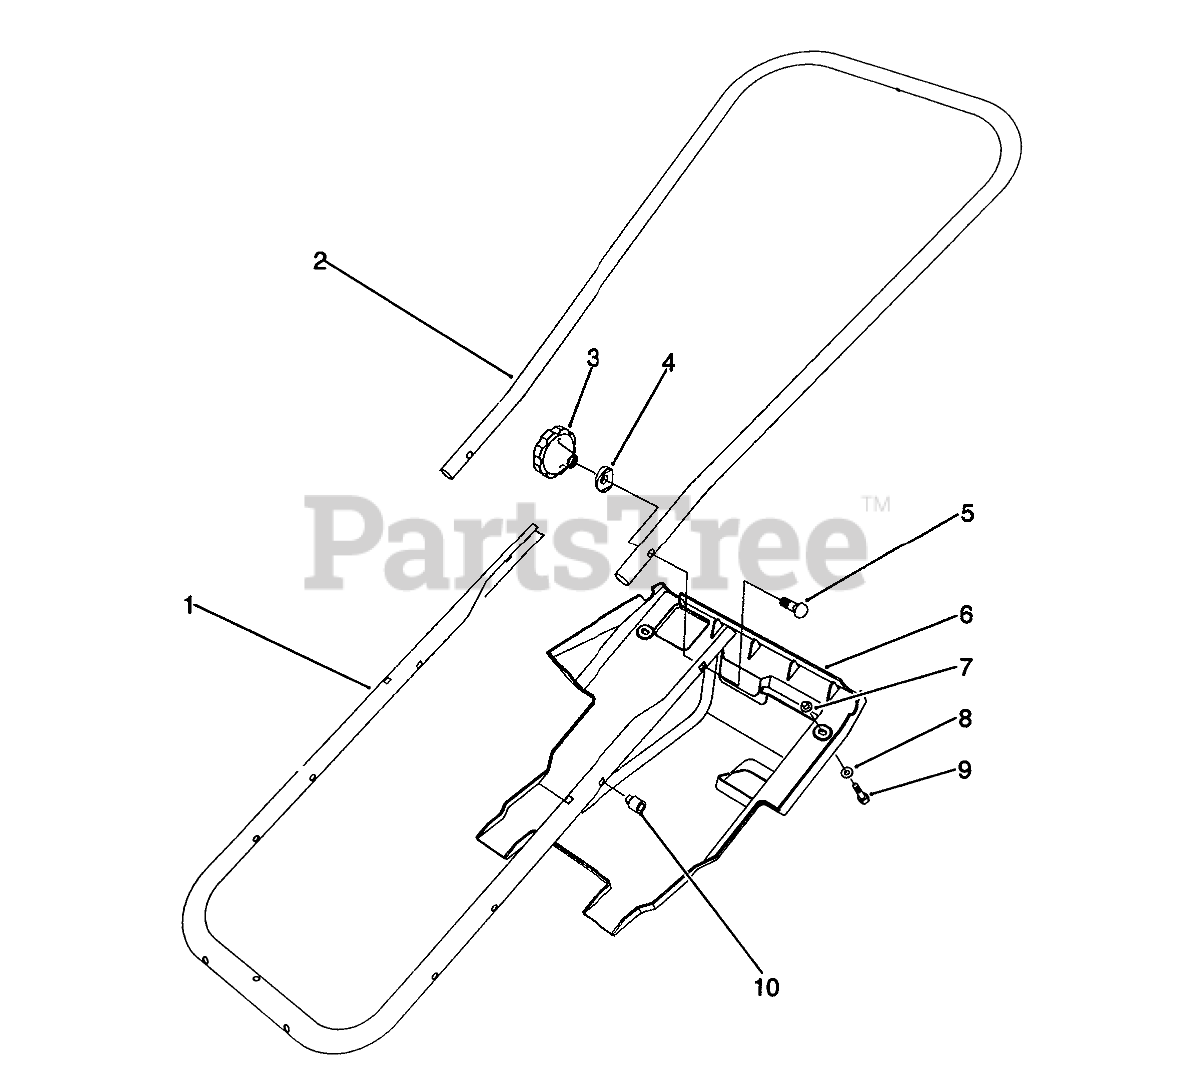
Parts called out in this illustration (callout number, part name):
1	Tube-Frame
2	Handle-Upper
4	WASHER-CURVED
5	SCREW-HANDLE
6	SHROUD
7	Nut-Push
8	WASHER-FLAT
9	SCREW-HWHTF
10	NUT-EXPANSION
11	Decal-Warning (Model No. 38196)
